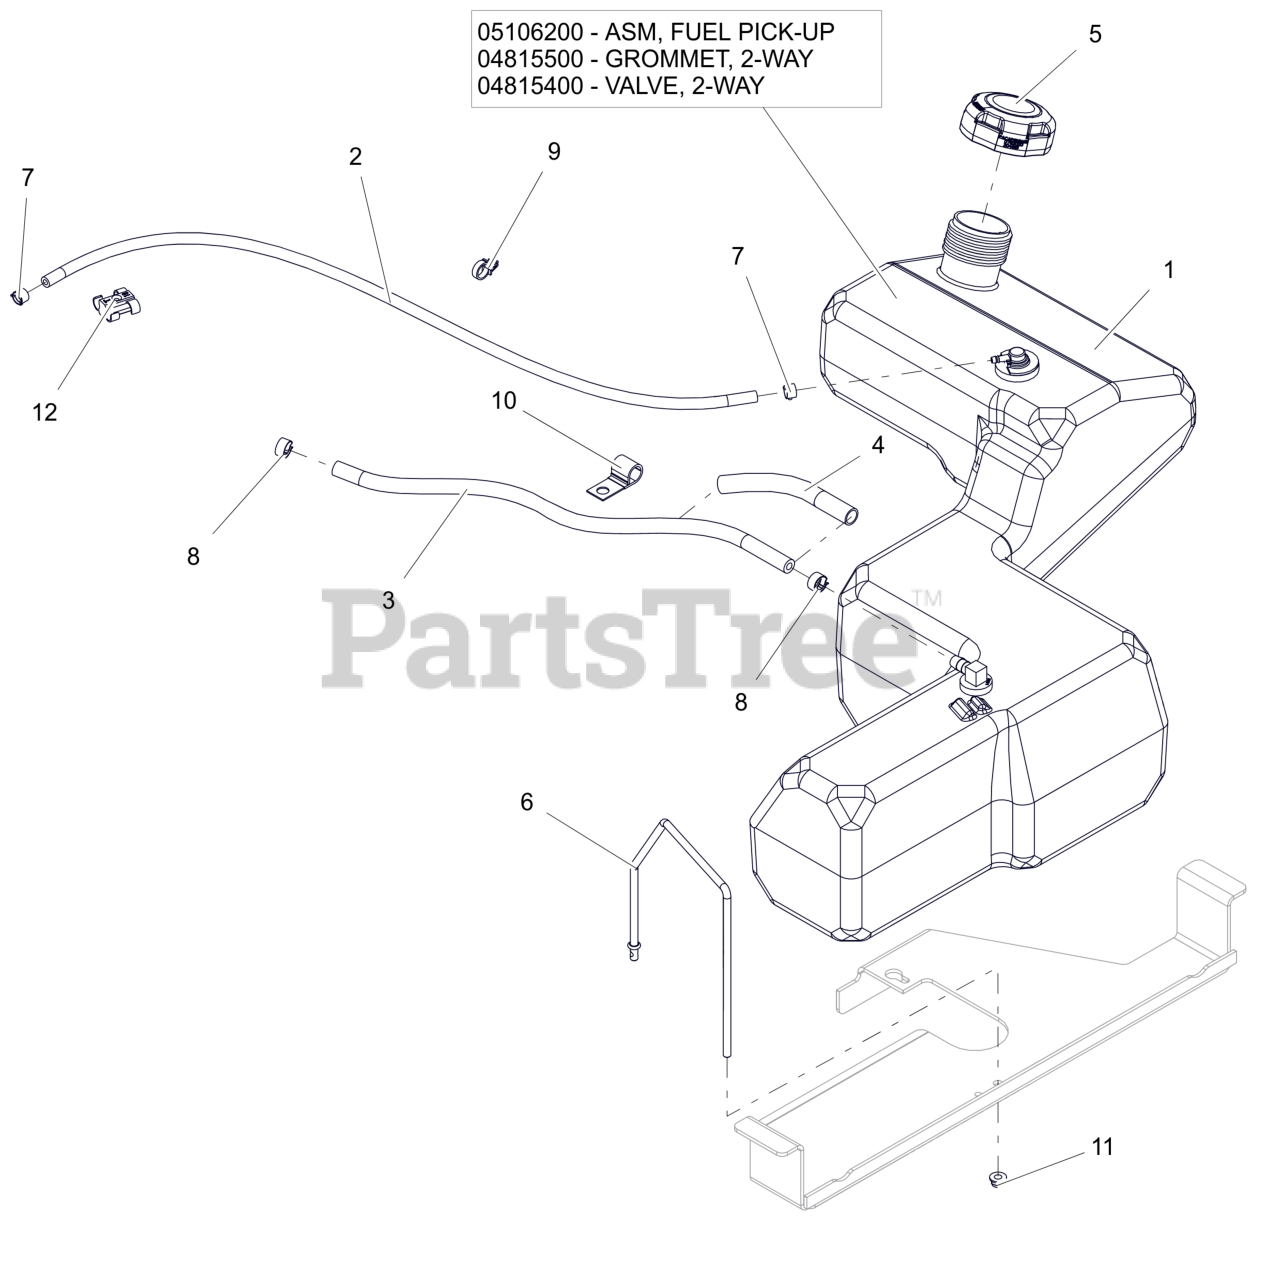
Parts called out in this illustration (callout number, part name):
1	ASM, FUEL TANK-IKON
1	ASM, IKON FUEL PICK-UP
1	GROMMET, 2-WAY
1	VALVE, 2-WAY
2	HOSE, .188 LOW-PERM BULK GAS
3	HOSE, .25 LOW-PERM BULK GAS
4	WRAP, ANTIABRASION .5X.064WALL
5	CAP, FUEL - 2.25 RATCHET INLET VENT
6	BRKT, FUEL TANK HOLD DOWN
7	CLAMP-HOSE, SPRING .188
8	CLAMP, FUEL LINE
9	ROUTING CLIP (1/2" ID)
10	J-CLAMP
11	NUT,NYL-FLG .25-20 GF ZCC
12	CLIP, T, .38-.50
